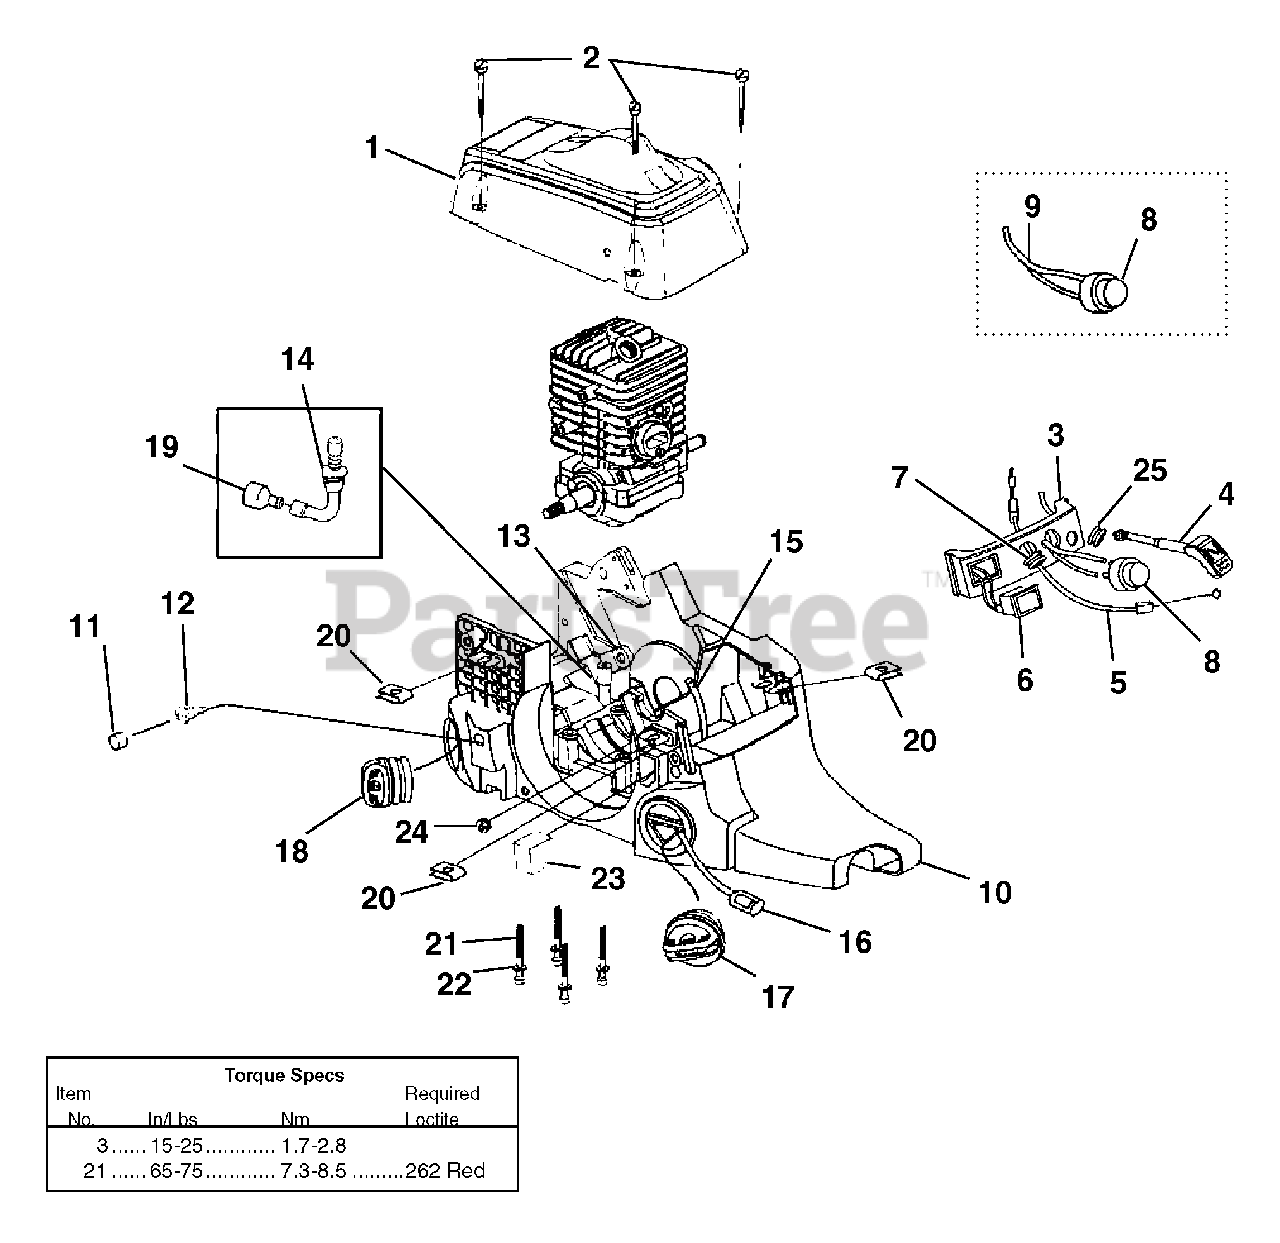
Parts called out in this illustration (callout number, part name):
1	Cylinder Cover Kit
2	Screw-Slotted Pan Hd.
3	Control Panel
4	Rod, Choke
5	Throttle Cable
6	Switch, Rocker
7	Grommet - Split
8	Primer Bulb
9	Rubber Tubing (5 1/2")
10	Chassis
11	Element, Filter (Bronze)
12	Duck Bill Valve
13	Oil Outlet Grommet
14	Oil Intake Tube w/Filter
15	Rubber Tubing (8 1/2")
16	Fuel Filter
17	Fuel Cap w/ Retainer
18	Oil Cap w/ Retainer
19	Oil Filter
20	Speed Nut ("U-Type")
21	Screw, Cap-Socket Hd. (10-24 x 2")
22	Washer
23	Pre Filter
24	Grommet-Split
25	Grommet
